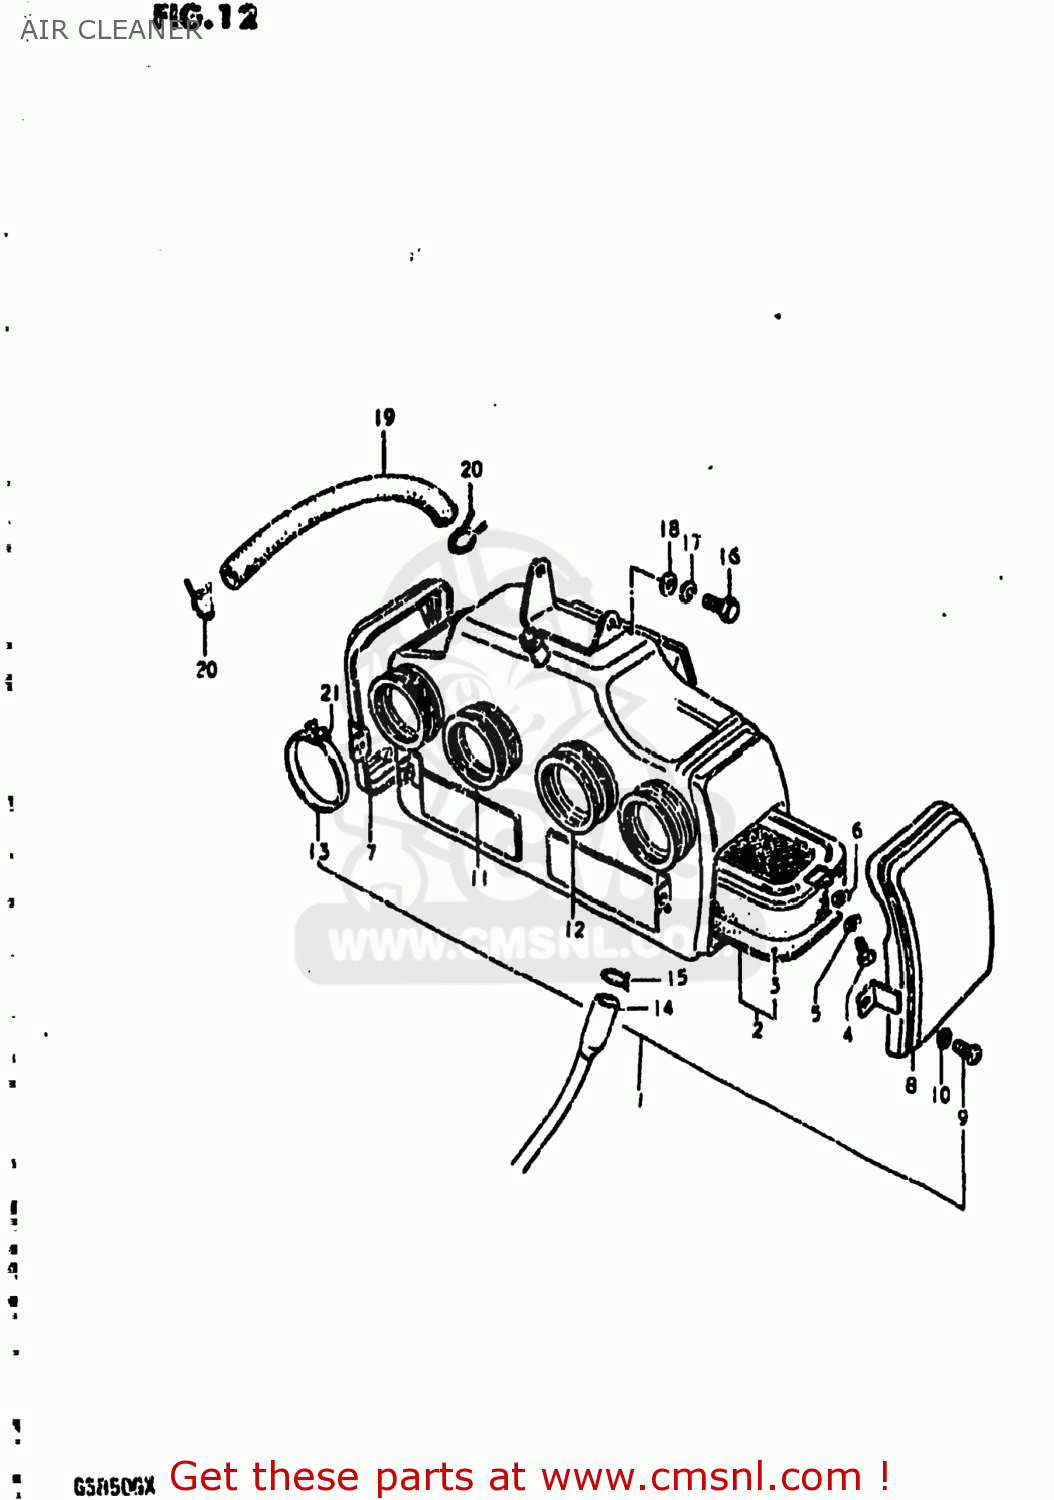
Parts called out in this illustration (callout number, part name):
1	CLEANER ASSEMBLY,AIR
2	FILTER ASSY,AIR CLEANER
3	FILTER
4	SCREW
5	LOCK WASHER
6	WASHER
7	CAP,AIR CLEANER
8	COVER, LH
9	SCREW
10	WASHER
11	HOSE,R
12	HOSE,L
13	CLAMP
14	HOSE
15	16
16	BOLT
17	LOCK WASHER
18	WASHER 6MM
19	HOSE
20	CLIP
